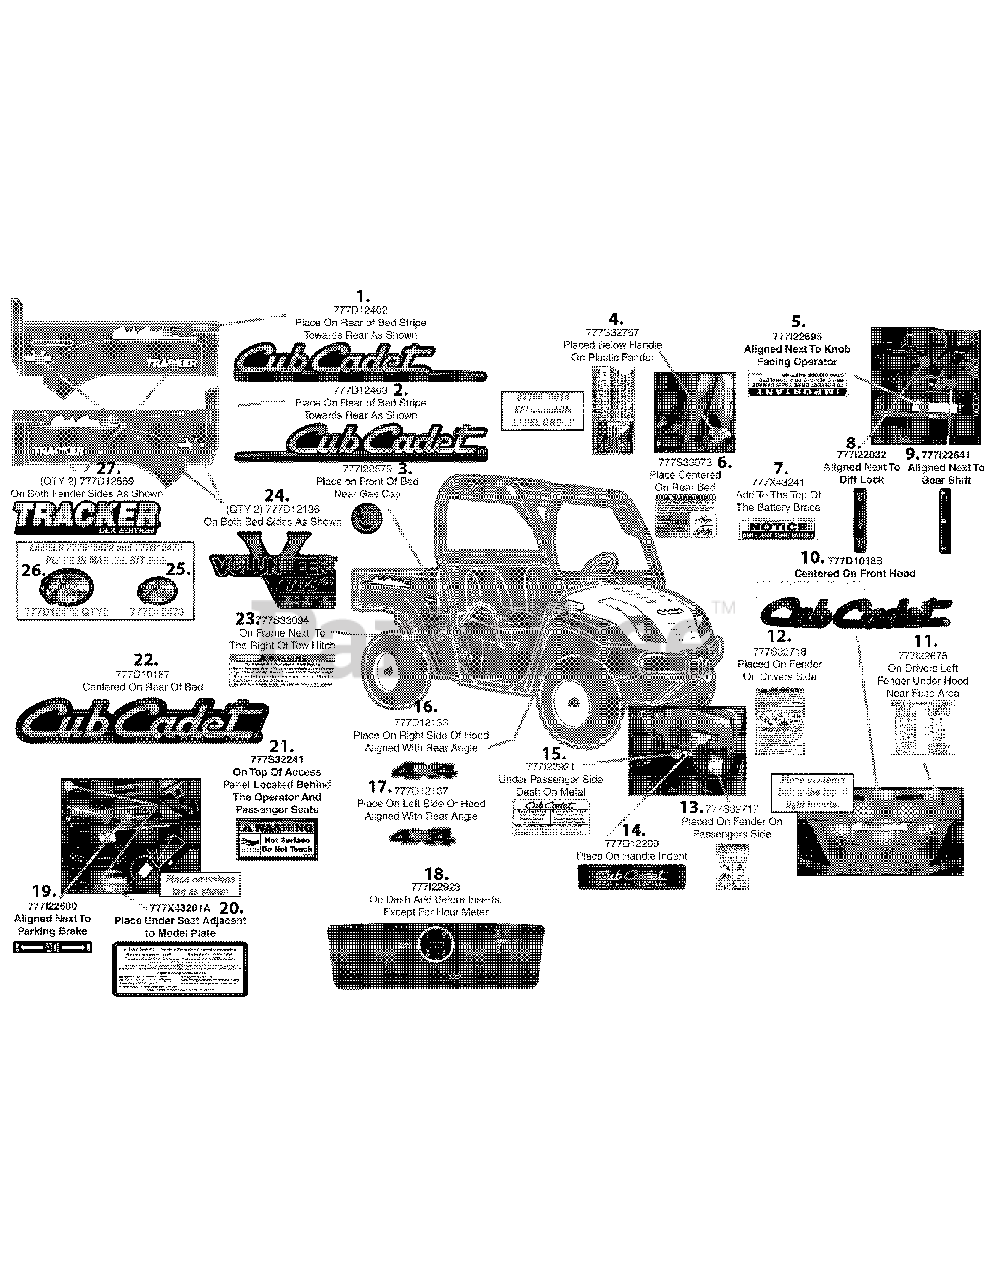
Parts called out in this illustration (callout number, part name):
1	LABEL-UV CUB CAMO EURO LH
2	LABEL-UV CUB CAMO EURO RH
3	LABEL-CHECK ENG OIL
4	LABEL-4X4 CARGO BOX HANDLE
5	LABEL:4X4 SHIFT
6	LABEL:UV:4X4 CARGO BOX EFI
7	LABEL-DON'T JUMP BATTERY
8	LABEL-DIFF LOCK CO
9	LABEL-GEAR SHIFT
10	LABEL-CUB CADET HOOD
11	LABEL:UV:4X4 CAT FUSE
12	LABEL-ROLL & FALL LH FENDER
13	LABEL-RIDER FALL RH FENDER
14	LABEL-UV DASH LOGO CAMO
15	LABEL:UV:EFI WEIGHT
16	LABEL:CUB UV:4X4 HOOD RT SD EFI
17	LABEL:CUB UV:4X4 HOOD LT SD EFI
18	LABEL:UV:EFI DASH CK ENG
19	LABEL-PARK BRAKE
20	LABEL-UV:EFI EMISSIONS
21	LABEL-HOT SURFACE
22	LABEL-CUB CADET BED
23	LABEL-SAFTEY:TOWING EFI 1400 LB
24	LABEL-UV VOLUNTEER OLIVE GREEN
25	LABEL:UTILITY:BASSPRO SMALL
26	LABEL:UTILITY:BASSPRO LARGE
27	LABEL:UV:TRACKER DLX FENDER
